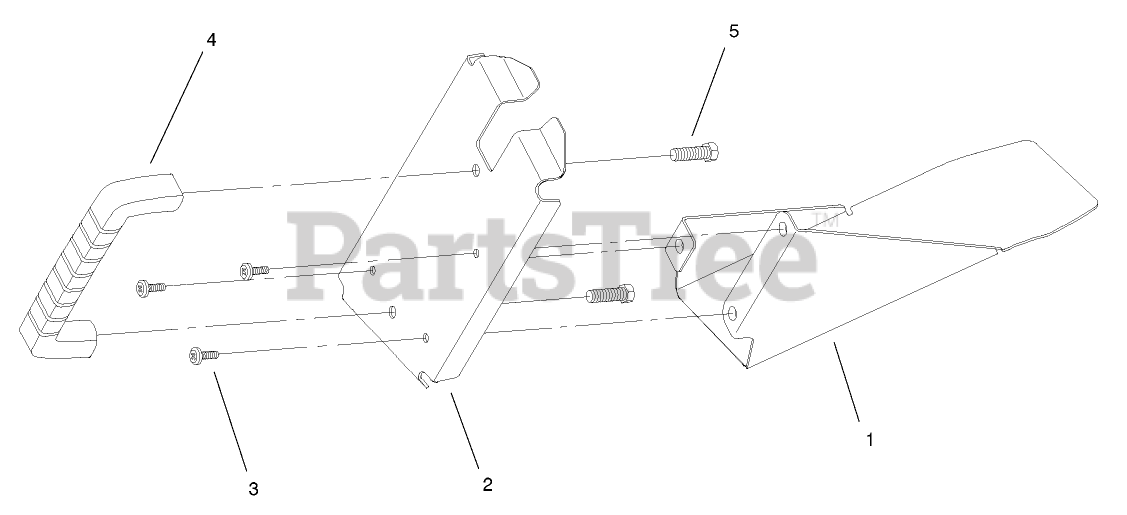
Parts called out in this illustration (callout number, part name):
1	SHIELD-DISCHARGE PLUG
2	COVER - DISCHARGE PLUG
4	HANDLE-DOOR
5	SCREW-HWH
